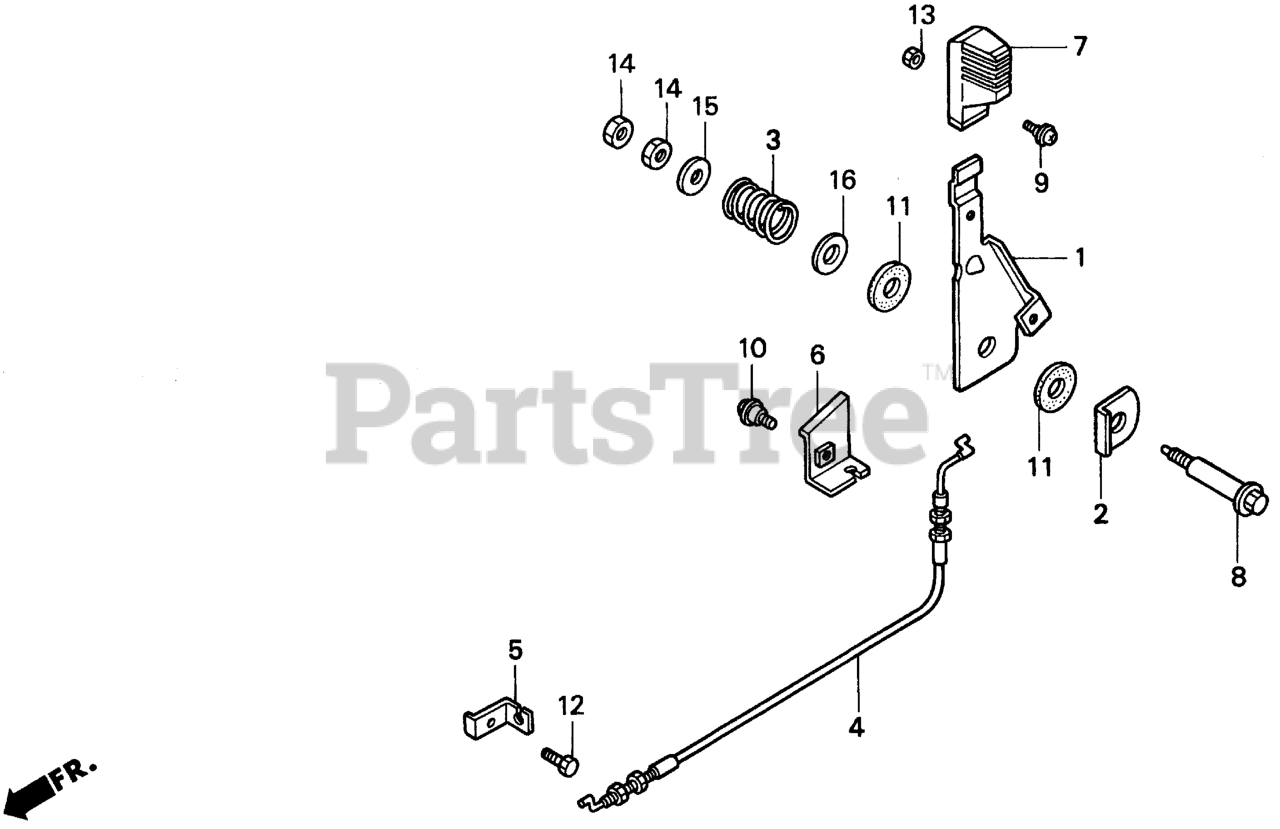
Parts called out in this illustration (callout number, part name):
1	LEVER, THROTTLE
2	PLATE, THROTTLE LEVER
3	SPRING, THROTTLE LEVER
4	CABLE, THROTTLE
5	HOLDER, CABLE
6	HOLDER, THROTTLE CABLE
7	KNOB B, CHANGE LEVER *YR161* (ORANGE)
8	BOLT, HEAD COVER
9	SCREW, HEADLIGHT SETTING
10	SCREW, SIDE COVER SETTING
11	WASHER, FRICTION
12	BOLT, RECESSED (5X16)
13	NUT, HEX. (5MM)
14	NUT, HEX. (6MM)
15	WASHER, PLAIN (6MM)
16	WASHER, PLAIN (12MM)
